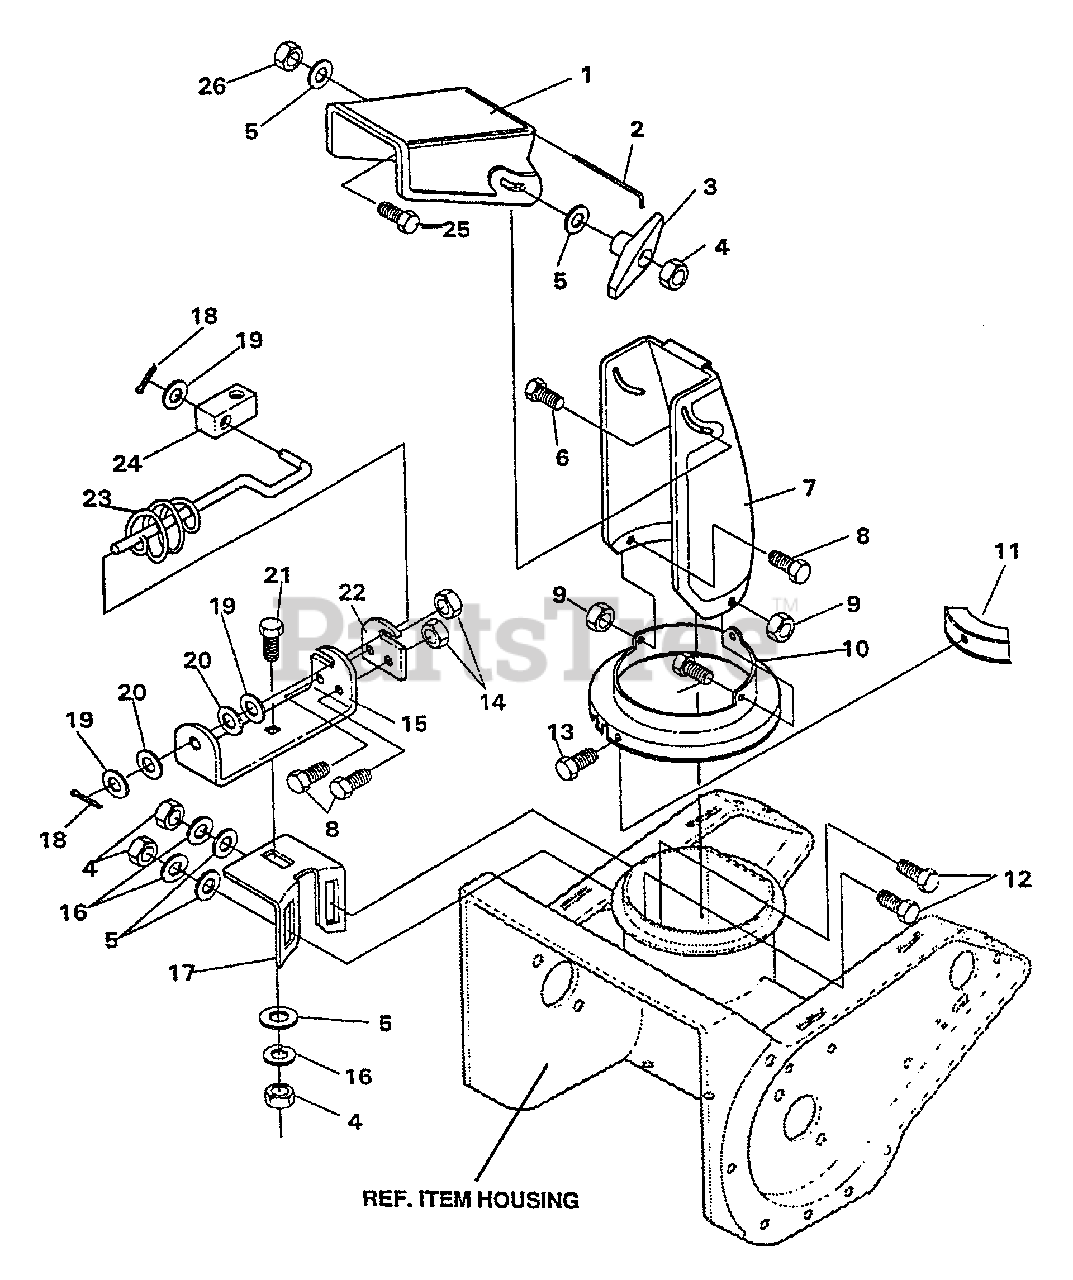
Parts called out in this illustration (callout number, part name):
1	CHUTE, UPR SRS W/OHKLE
2	WIRE, HINGE 6.65 LONG SR
3	KNOB, T 2 BLADE W/5/16-18 NUT
5	WASHER
6	BOLT 5/16"-18×1.25" CARRLN
7	CHUTE, LWR
8	SCREW 1/4"-20×0.50
9	NUT, 1/4"-20
10	RING, LWR CHUTE
10	RING, LOWER CHUTE
11	CLIP, CHUTE RING PLASTIC
12	BOLT, CARRIAGE 5/16-18×0.75
13	SCREW 1/4"-14×0.63
14	NUT, 1/4"-20
15	BRACKET, CHUTE ROD
16	WASHER
17	BRACKET, WORM ADJUST
18	PIN - COTTER
19	WASHER - 0.40×0.75×0.025"
20	WASHER, SADDLE
21	BOLT, CARRIAGE 5/16-18×0.75
22	PLATE, CHUTE ROD
23	ROD ASSY, CHUTE CONTROL LOWER
24	BLOCK, PIVOT PLASTIC
25	SCREW 5/16"-18×0.75
26	NUT, 5/16"-18
